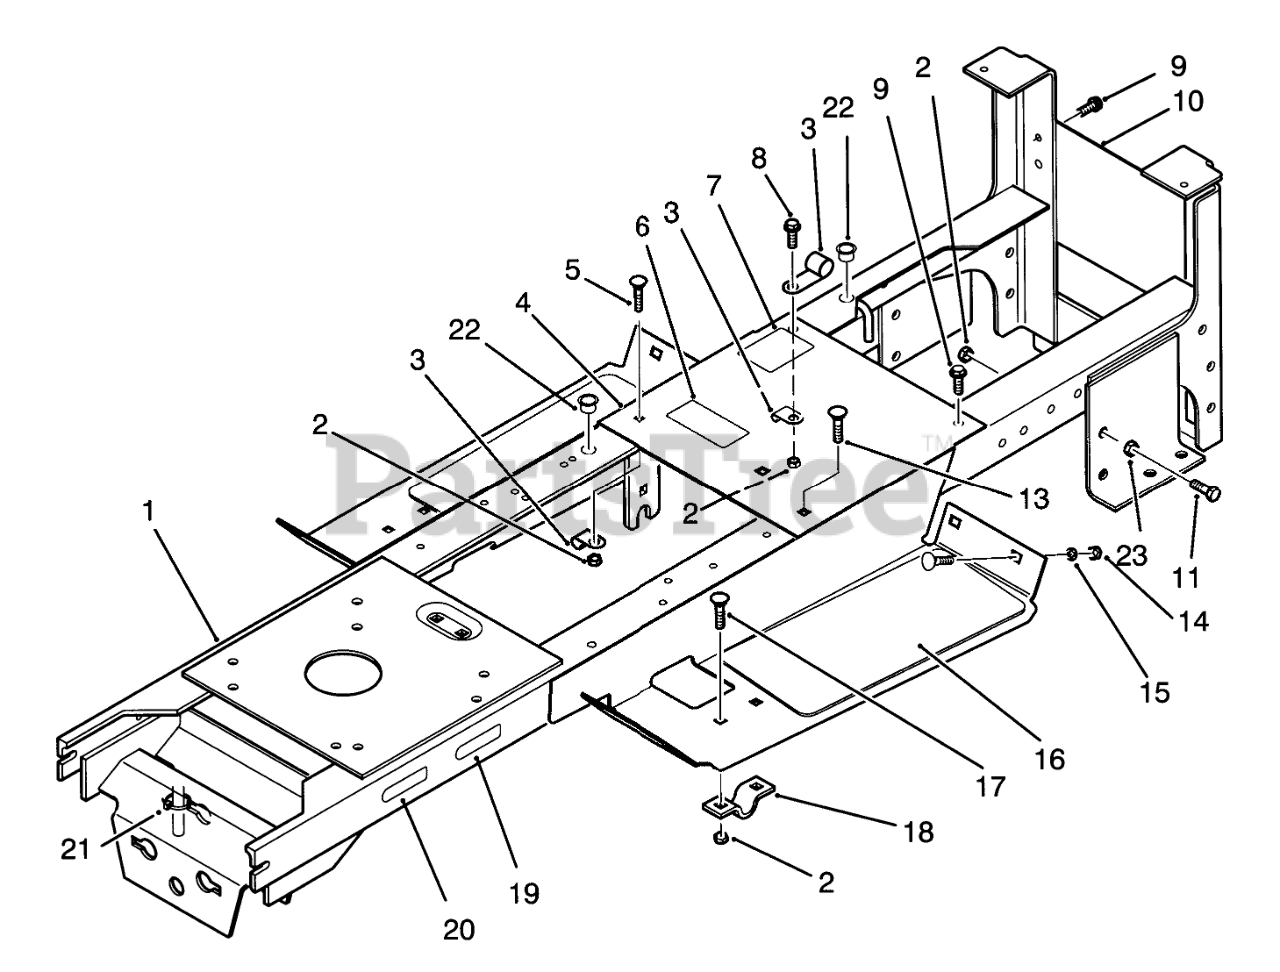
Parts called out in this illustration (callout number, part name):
1	WEDMT-FRAME R
2	NUT-LOCK, NI
3	THROTTLE CONTROL CLP
4	Panel (Incl. Ref. #6)
5	Bolt-Carriage
6	DECAL-DANGER
7	DECAL-PARKING BRAKE
8	Bolt
9	SCREW
10	PANEL-REAR R
11	SCREW-HH
13	Bolt-Carriage
14	NUT-HEX
15	WASHER - FLAT YZ
16	PAD FOOTREST
17	Bolt-Carriage
18	CLAMP
19	Decal-Attac-O-Matic
20	DECAL-INSTALL BELT
21	PLASTIC TIE
22	BUSHING
23	NUT-JAM
